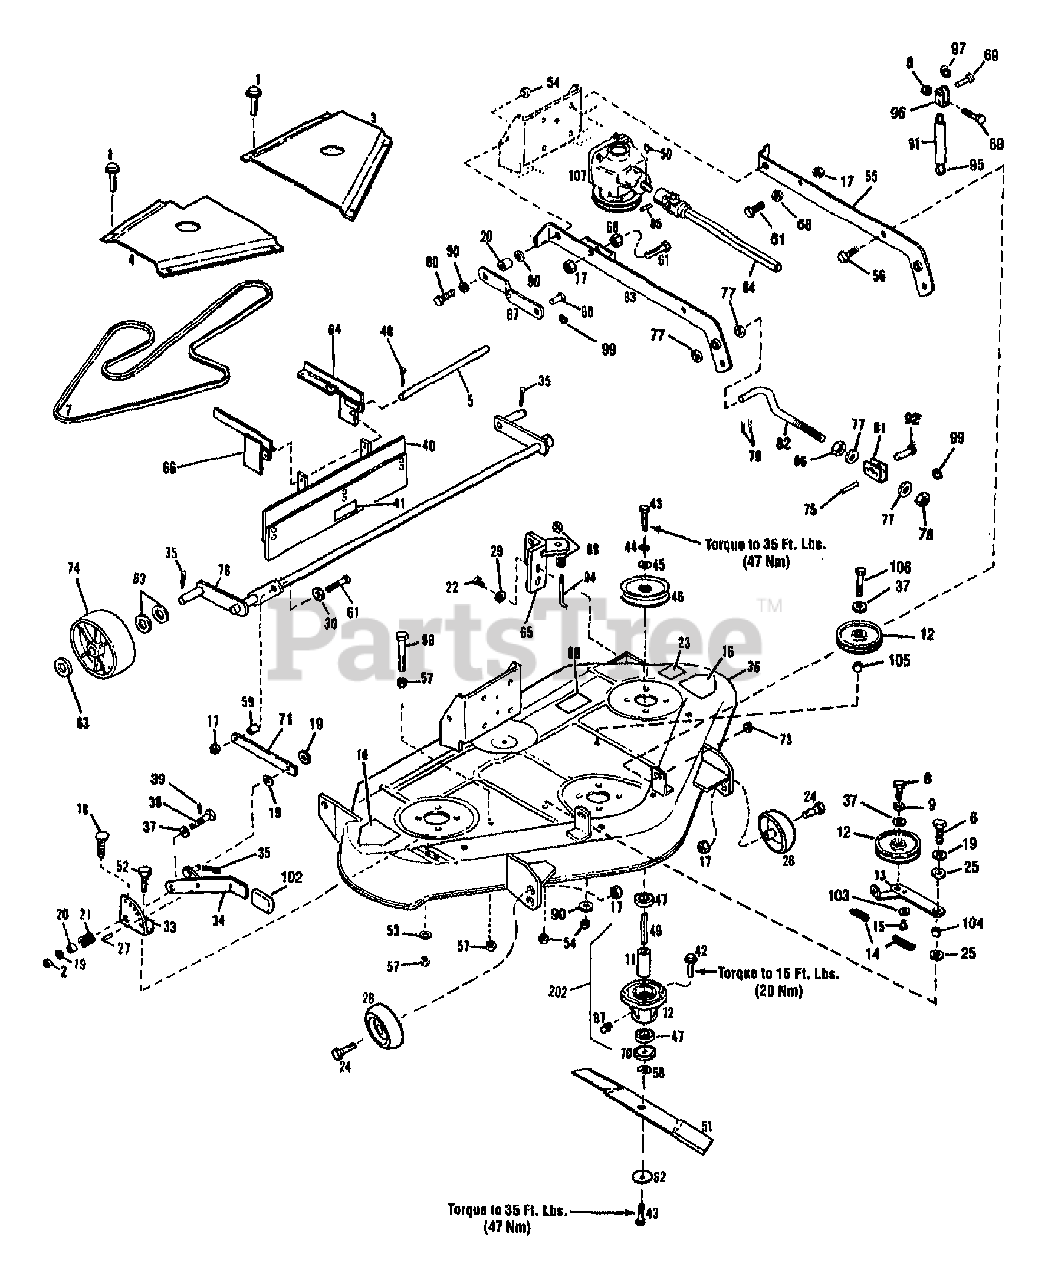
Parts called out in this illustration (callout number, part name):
1	SCR 1/4-20X.5 FL SELF TAP
3	COVER-BELT LH
4	COVER-BELT RH
5	ROD-GUARD
6	SCR-HH 1/2-13X1.5 G5 ZP
8	SCR-HH 1/4-20X1.25 G5 ZP
9	WASHER-LK .5
12	PULLEY-IDLER
13	ARM-IDLER
15	BUTTON-WEAR
16	DECAL-OPEI CAUTION
17	NUT-LOCK 3/8-16
18	SCR-CARR 5/16-18X.75 G2 ZP
19	WASHER-1.06X.531X.1 ZP
20	SPACER-TUBULAR
21	SPRING
22	SCR-HH 3/8-16X1.0 G5 ZP
23	DECAL-WARNING
24	SCR-SHLDR 3/8-16
25	WASHER
26	WHEEL-GAGE
27	PIN-.312X.75
29	WASHER-.986X.437X.083 ZP
30	WASHER-FLAT 3/8 SAE
34	LEVER-HEIGHT ADJUST
35	PIN-COTTER .120X1.00 ZP
36	ASSM-BASE W/DECALS 48" RD
37	WASHER-FLAT .88X.5X.06 ZP
40	ASSM-GUARD
41	DECAL-WARNING
42	SCR-HFLK 5/16-18X.75
43	SCR-HH 1/2-14X1.00
44	WASHER-LK .438 ZP
45	WASHER-1.25X.5X.083 ZP
46	ASSM-SHEAVE DRIVE
47	BEARING-BALL
48	PIN-COTTER .093X.50 ZP
49	SHAFT-SPINDLE
50	KEY-WOODRUFF .188X.75
51	BLADE-CUTTER
52	SCR-HHC 5/16-18X.75 GR 5 ZP
53	WASHER-FLAT 5/16 SAE
54	NUT-TOP LOCK 1/2-13 ZP
55	SUPPORT-DECK LH
56	SCR-HFLK 3/8-16X1.00 ZP
57	NUT-TOP/LK 5/16-18 ZP
58	RING-RETAINING EXT .694 ID
59	SPACER-.625X.39X.343
60	PIN-CLEVIS .625X1.44
61	SCR-HH 3/8-16X1.5 G5 ZP
62	WASHER-BELLEVILLE
63	WASHER-1.305X.649X.098 ZP
64	STOP-DISCHARGE GUARD RH
65	SUPPORT-SHAFT
66	STOP-DISCHARGE GUARD LH
67	LINK-DRAG
68	NUT-HEX/JAM 3/8-16 ZP
69	PIN-CLEVIS
70	SPACER-BLADE
71	LINK-CONNECTING
72	HOUSING-SPINDLE
73	NUT-HFLK 3/8-16 ZP
74	WHEEL-GAGE
75	PIN-DRIVE
76	SHAFT-PIVOT
77	WASHER-1.38 X.765X .06 ZP
78	NUT-H/LK 3/4-10
79	PIN-COTTER .120X1.25 ZP
80	SCR-HH 1/2-13X1.75 G5 ZP
81	BRKT-HITCH
82	LINK-HITCH
83	SUPPORT-DECK RH
84	ASSM-DRIVESHAFT
85	PIN-DRIVE
86	NUT
87	FITTING-GREASE 1/4-28X2.00
88	DECAL-BELT DRIVE
89	SCR-HH 5/16-18X1.25 G5ZP
90	WASHER-1/2 FLAT
91	SLEEVE-CHAIN
92	PIN-CLEVIS .62X2.50 ZP
94	BOLT-HOOK
95	KIT-CHAIN
96	CLEVIS
97	RING-CIRCLE COTTER
98	NUT-H/LK 5/16-18
99	RING-COTTER
102	GRIP-HANDLE
103	WASHER-.505X.22X.05
104	SLEEVE-BEARING
105	SPACER-TUBULAR
106	SCR-HH 1/2-13X2.0 G5 ZP
107	ASSM-GEAR CASE
202	ASSM-MOWER SPINDLE
